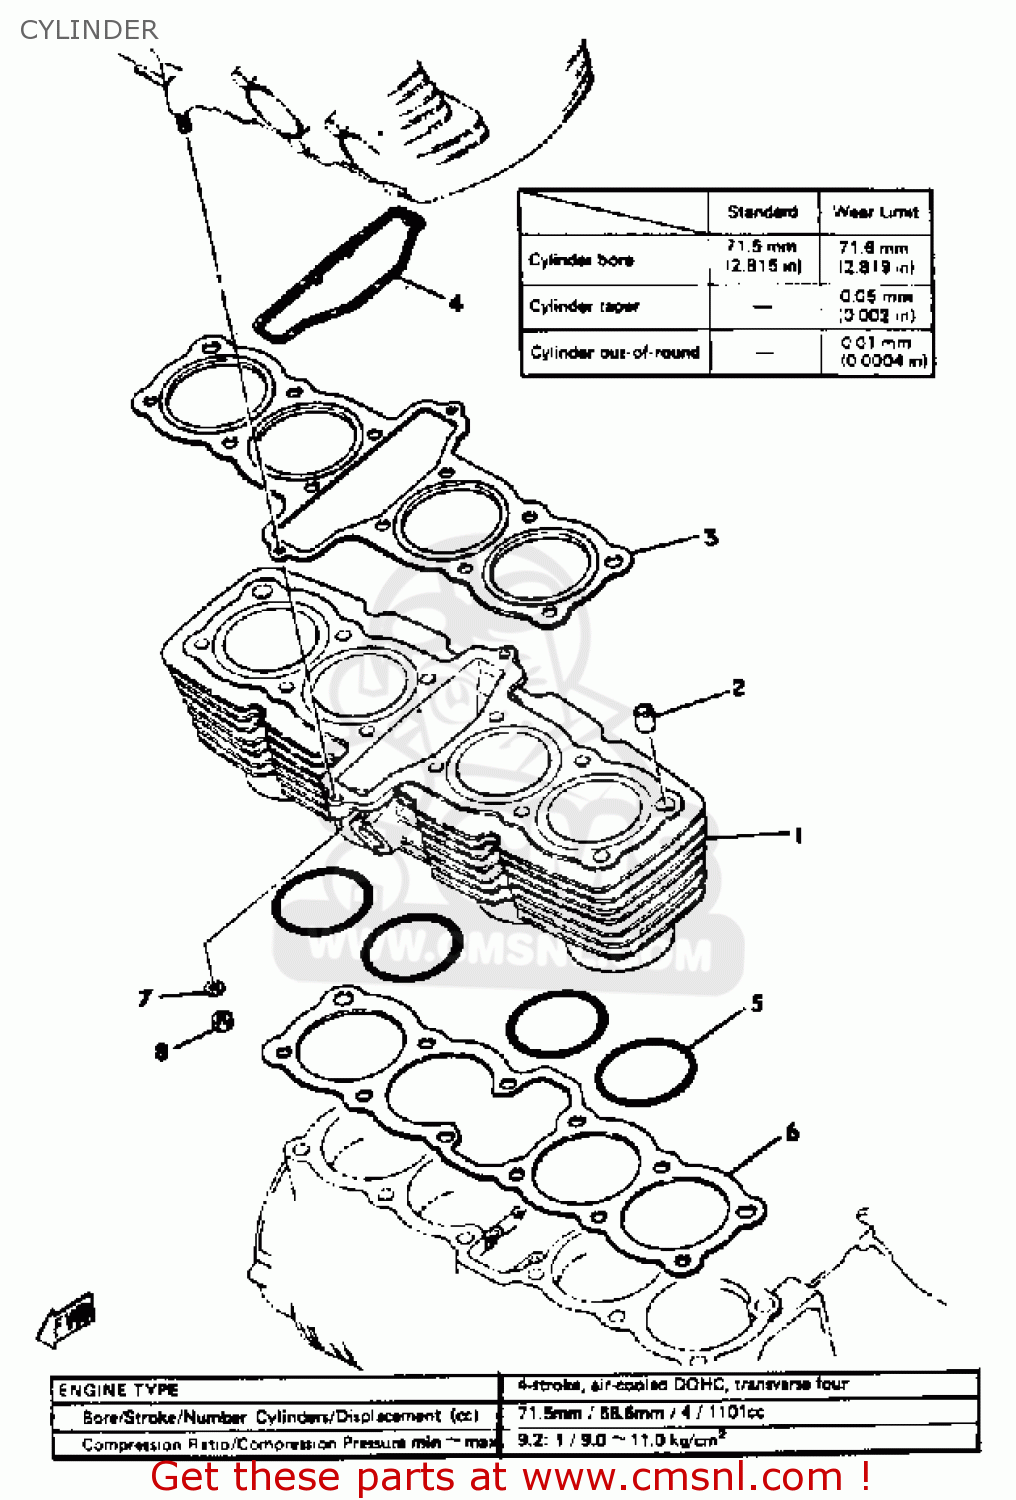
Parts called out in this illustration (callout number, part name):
1	CYLINDER
2	PIN, DOWEL
3	GASKET, CYLINDER HEAD (NAS)
4	SEAL, CYLINDER
5	O-RING (2H7)
6	GASKET, CYLINDER
7	WASHER, PLATE (33N)
8	NUT(6L2)
